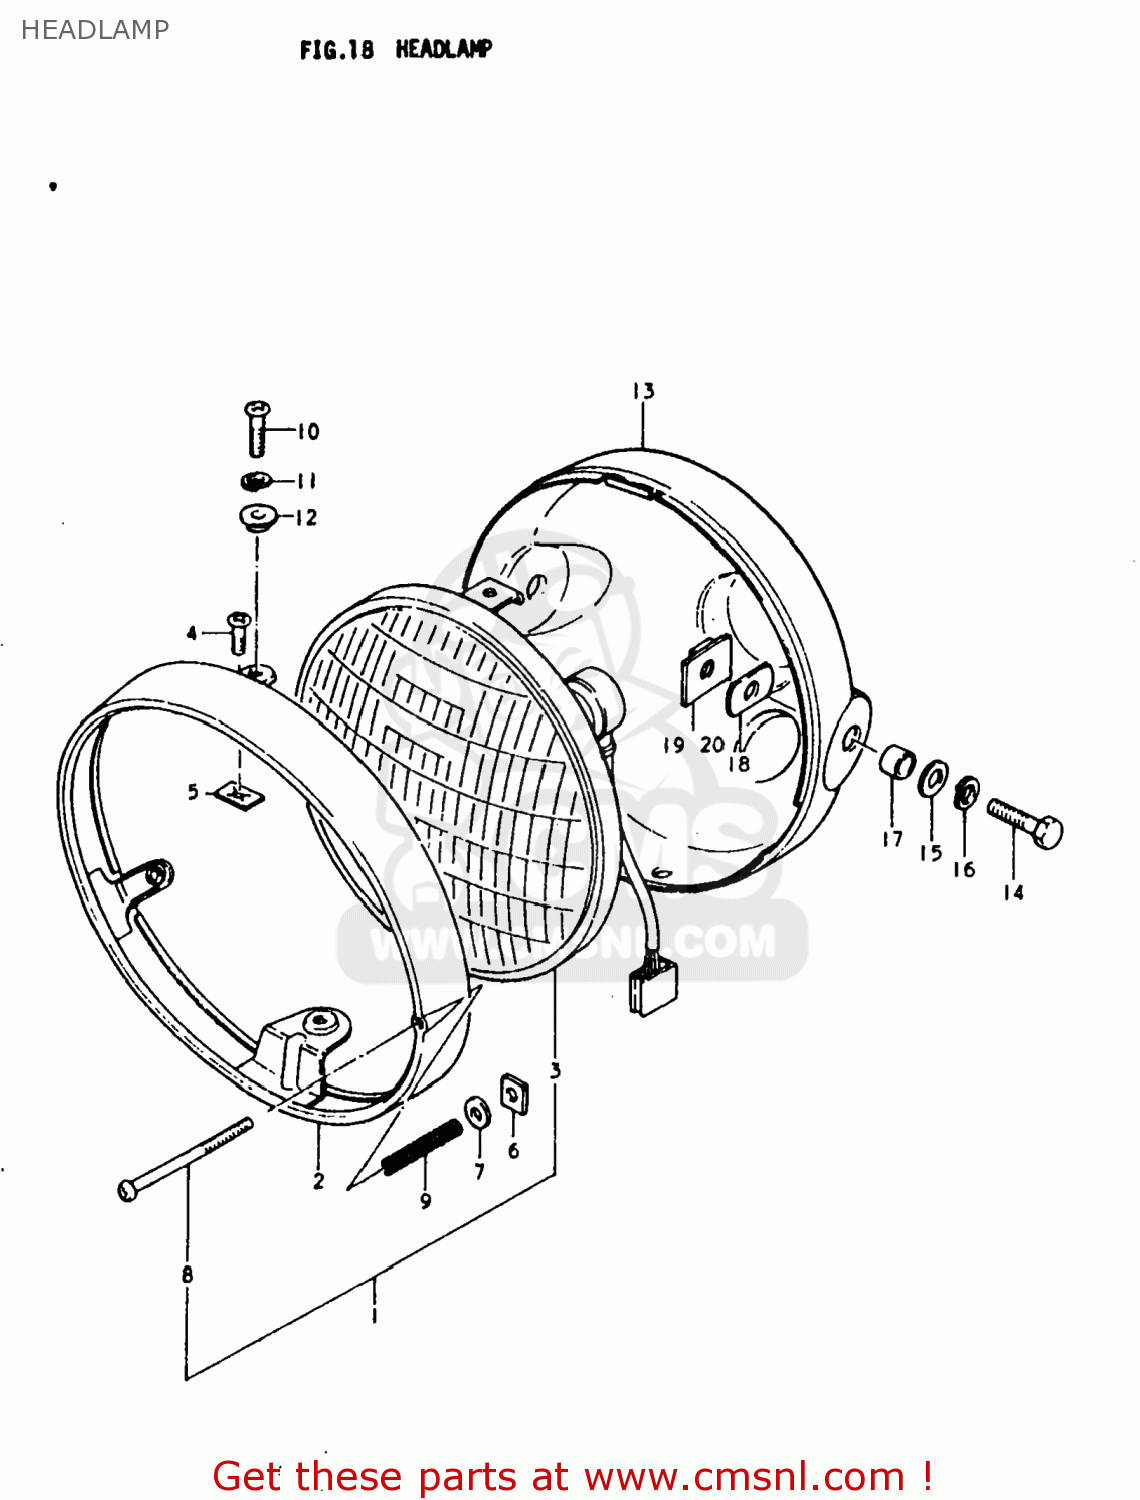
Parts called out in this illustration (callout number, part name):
1	LAMP ASSEMBLY,HEAD
2	RIM,HEADLAMP
3	RETAINER
4	LAMP UNIT
5	SCREW
6	LOCK WASHER
7	SPRING,HEAD LAMP UNIT
8	COVER
9	SCREW
10	SPRING,HEADLAMP ADJUST
11	NUT
12	COVER, FITING
13	SCREW
14	LOCK WASHER
15	WASHER
16	LEAD WIRE,HEADLAMP
17	HOUSING,HEADLAMP
18	BOLT
19	WASHER
20	LOCK WASHER
21	SPACER (8.8X12X7)
22	CUSHION
23	PLATE,HEADLAMP HOUSING
24	PLATE,HEADLAMP HOUSING
